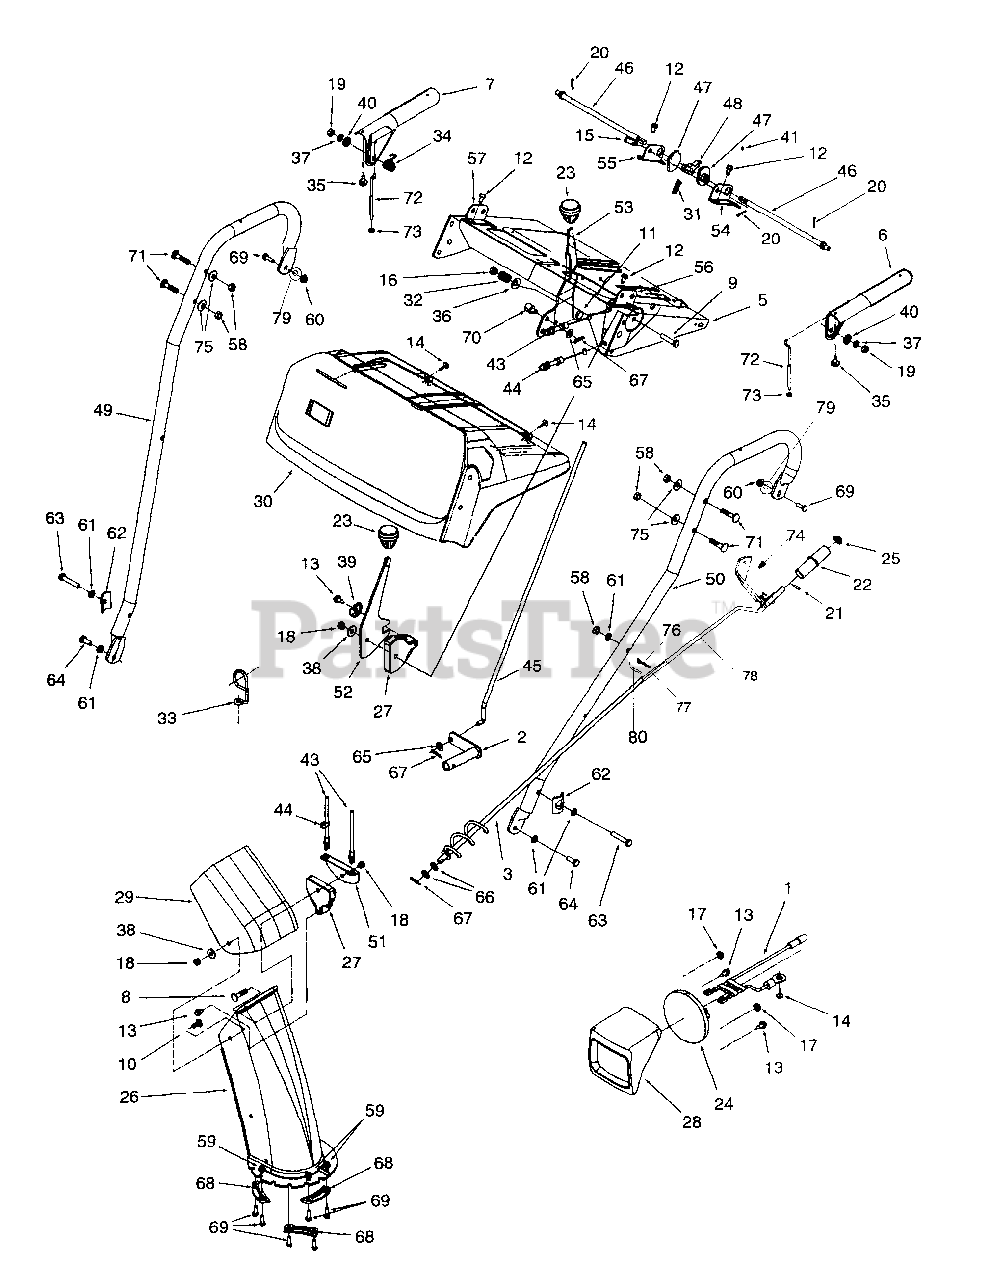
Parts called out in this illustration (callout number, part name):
1	Harness for Headlight
2	Shift Arm Assembly
6	Handle Assembly Engagement (L.H.)
7	Handle Assembly Engagement (R.H.)
8	Carriage Bolt 5/16-18 x 1.50
9	Hex Bolt 5/16-18 x 1.5
10	Carriage Bolt 5/16-18 x.75
11	Hex Screw 3/8-24 x 1.5
12	Hex Washer Hd. TT Screw 1/4-20 x 0.5"
13	Hex AB Tap Screw 1/4 x .62
14	Hex B-Tapp Screw # 10-16 x.62
15	Clevis Pin
16	Hex Ins. Lock Nut 3/8-24
17	Self Threading Nut
18	Lock Nut 5/16-18
19	Hex Nut
20	Cotter Pin
21	Roll Pin
22	Chute Crank Knob
23	Shift Knob
24	Headlight
25	Push Cap
26	Lower Chute
27	Cable Guide
28	Headlight Bezel
29	Upper Chute
30	Handle Panel
31	Compression Spring
32	Compression Spring
33	Cable Control Wire
34	Torsion Spring
35	Rubber Bumper
36	Bell Washer .380 x .880 x .062
37	Lock Washer 5/16 I.D.
38	Washer 5/6 I.D.
39	Special Washer
40	Special Washer
41	Grease
43	Chute Deflector Control Cable
44	Chute Deflector Cable w/ Clip
45	Shift Rod
46	Cam Rod
47	Cam Handle Lock
48	Pawl Handle lock
58	Hex Nut 5/16-18 Thd.
59	Hex Range Locked Nut 1/4-20 Thd.
60	Hex Nut 1/4-20
61	Lock Washer 5/16
62	Handle Tab
63	Hex Bolt 5/16-18 x 1.75 Gr.5
64	Hex Bolt
65	Flat Washer 5/16
66	Flat Washer 3/8 x .738 x .063
67	Hairpin Clip
68	Chute Flange Keeper
69	Hex Bolt 1/4-20 x 0.75" Gr.5
70	Ferrule
71	Carriage Bolt 5/16-18 x 1.50
72	Z Fitting
73	Hex Nut # 10-24
75	Cupped Washer .340 I.D. x .872 O.D.
76	Hairpin Clip
77	Spacer
79	Bell Washer
80	Roll Pin
